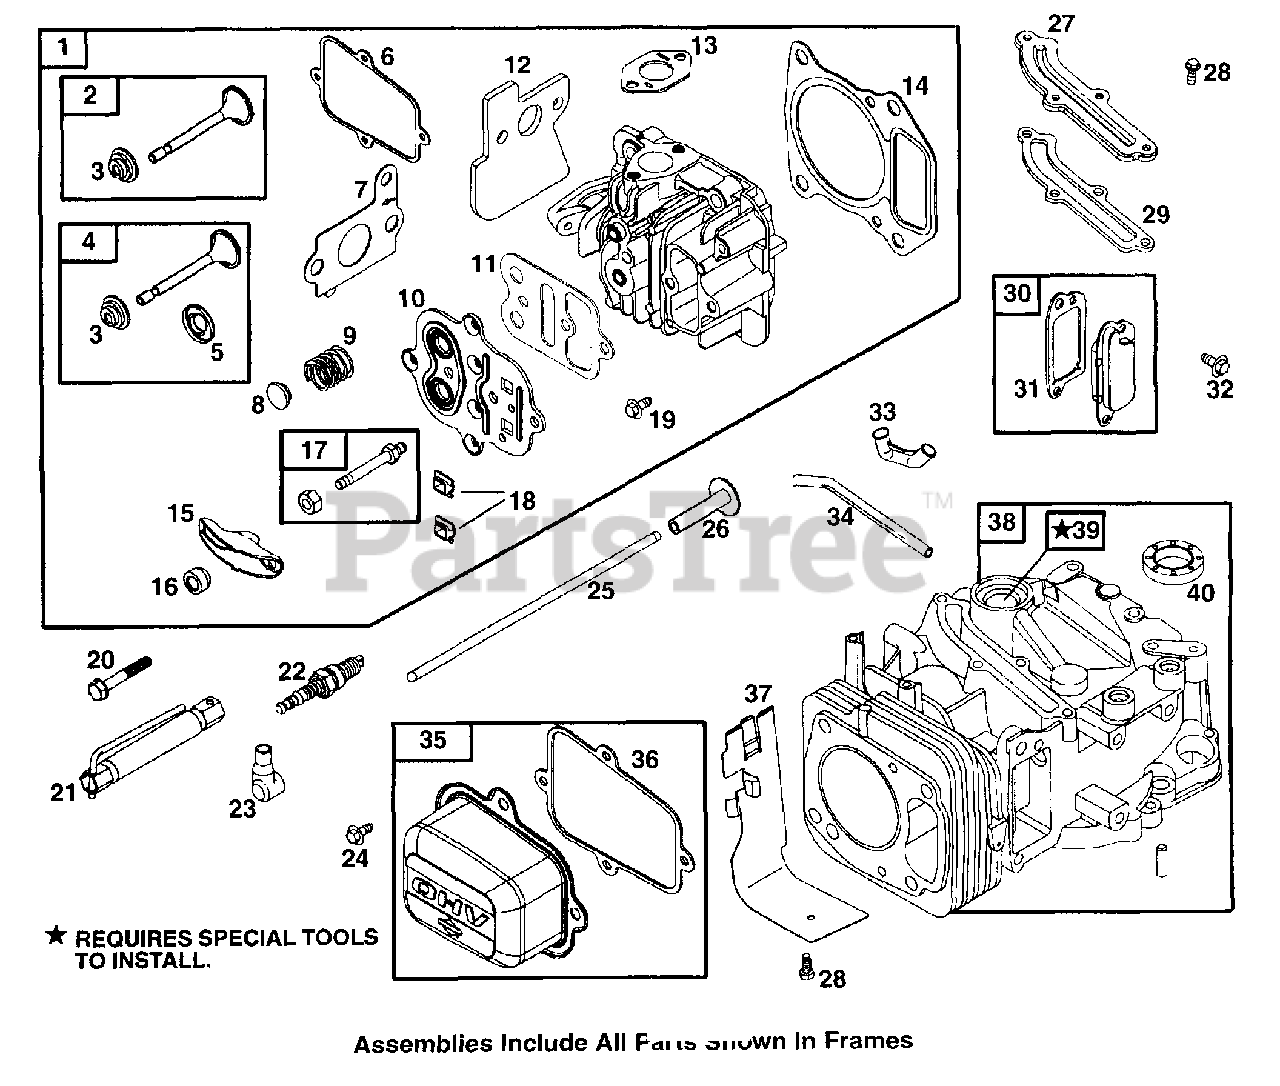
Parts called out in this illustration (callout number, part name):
1	Cylinder Head
2	Exhaust Valve
3	Valve Retainer
4	Intake Valve
5	Valve Seal
6	Rocker Cover Gasket
7	Intake Gasket
8	Valve Cap
9	Valve Spring
10	Cylinder Head Plate
11	Plate Gasket
12	Carburetor Spacer
13	Exhaust Gasket
14	Cylinder Head Gasket
15	Rocker Arm
16	Rocker Arm Ball
17	Rocker Arm Stud
18	Push Rod Guide
19	Hex Screw
20	Hex Screw
21	Spark Plug Wrench
22	Spark Plug
23	Spark Plug Boot
24	Hex Screw
25	Push Rod
26	Valve Tappet
27	Breather Passage Cover
28	Hex Screw
29	Breather Passage Gasket
30	Breather Assembly
31	Breather Gasket
32	Hex Screw
33	Grommet
34	Breather Tube
35	Rocker Cover
36	Rocker Cover Gasket
37	Cylinder Shield
38	Cylinder Assembly
39	Bushing/Seal Kit
40	Oil Seal
